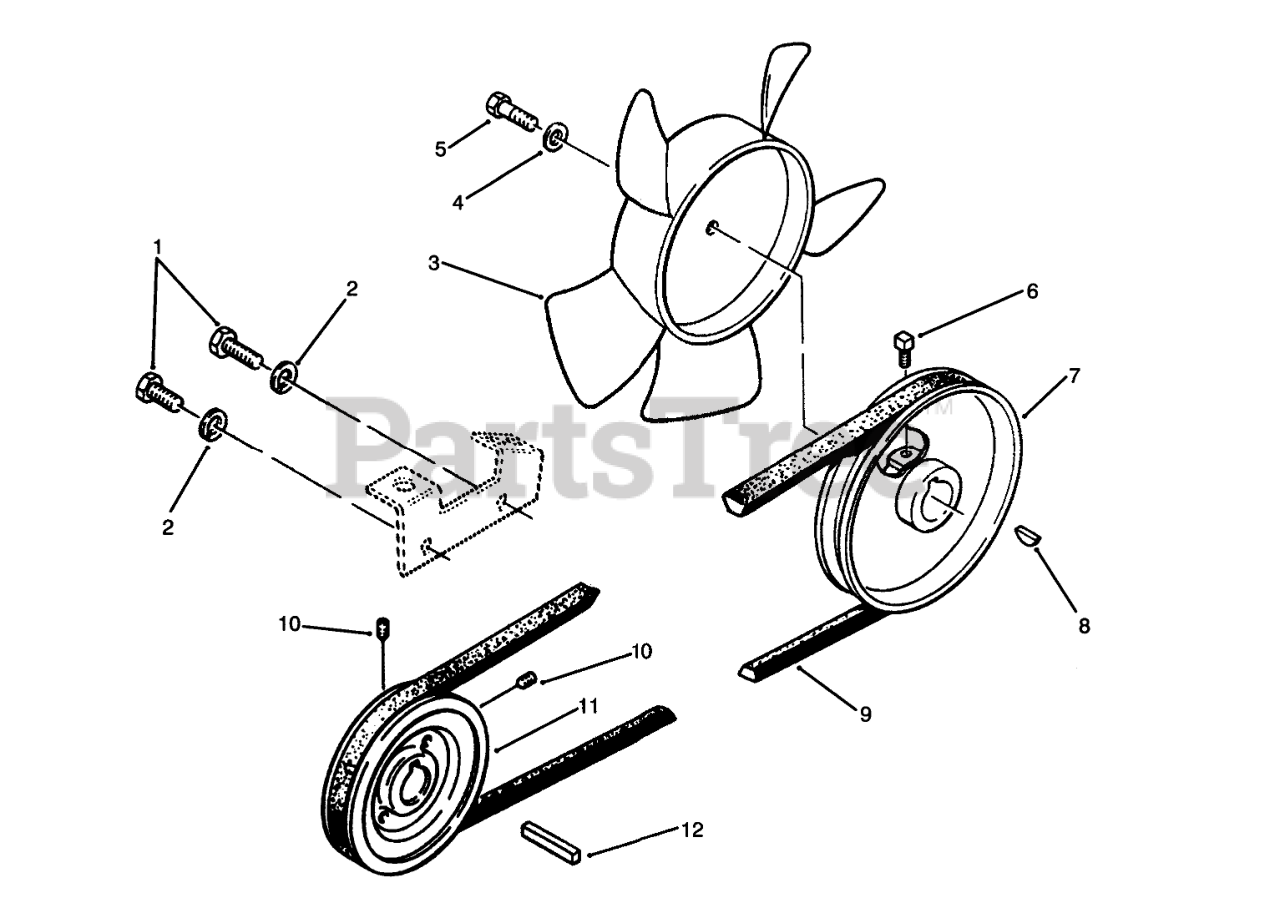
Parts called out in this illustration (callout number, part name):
1	SCREW-HH
2	WASHER-FLAT
3	NYLON FAN-L-CW
4	WASHER
5	SCREW-HH
6	SCREW-SQH
7	PULLEY
8	KEY-WOODRUFF
9	BELT-V
10	SCREW-SET, HSH
11	PULLEY
